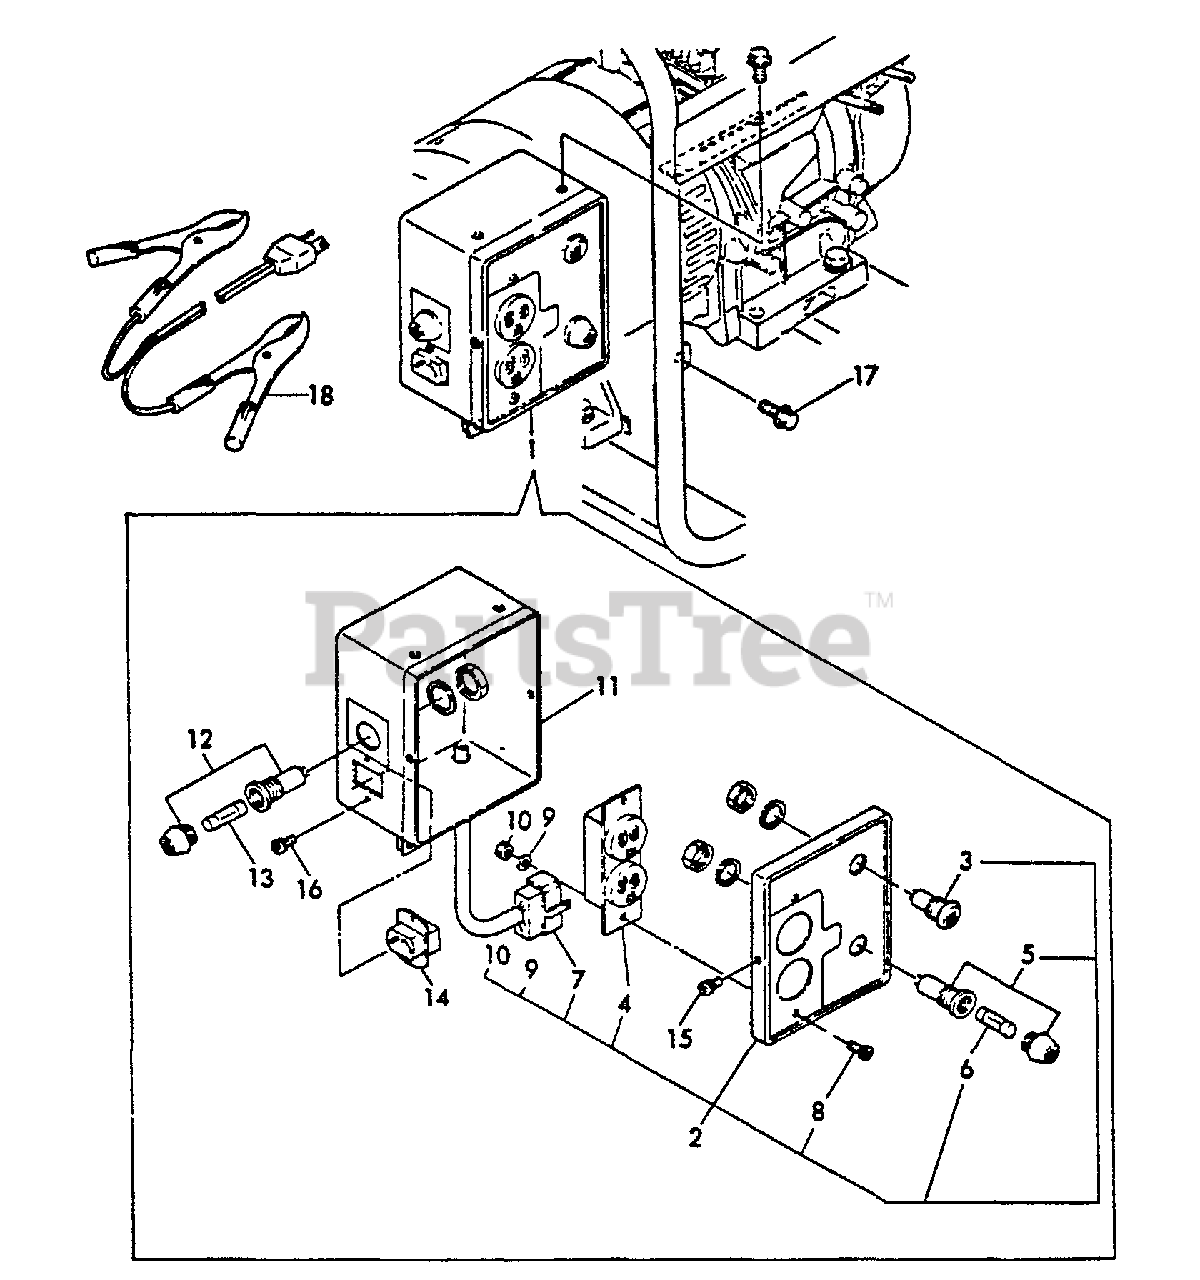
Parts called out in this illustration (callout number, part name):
1	PANEL BOX ASSY
2	PANEL ASSY
3	LAMP, PILOT - 100V
4	AC CONNECT
5	HOLDER, FUSE
6	FUSE - 12.8A
7	WIRE HARNESS
8	SCREW - 4×8
9	WASHER - 4
10	NUT - 4
11	BOX, PANEL
12	HOLDER, FUSE
13	FUSE - 15A
14	PLUG SOCKET 15A
15	SCREW - 4×8
16	SCREW - 3×10
17	BOLT - 6×8 -- PLATED
